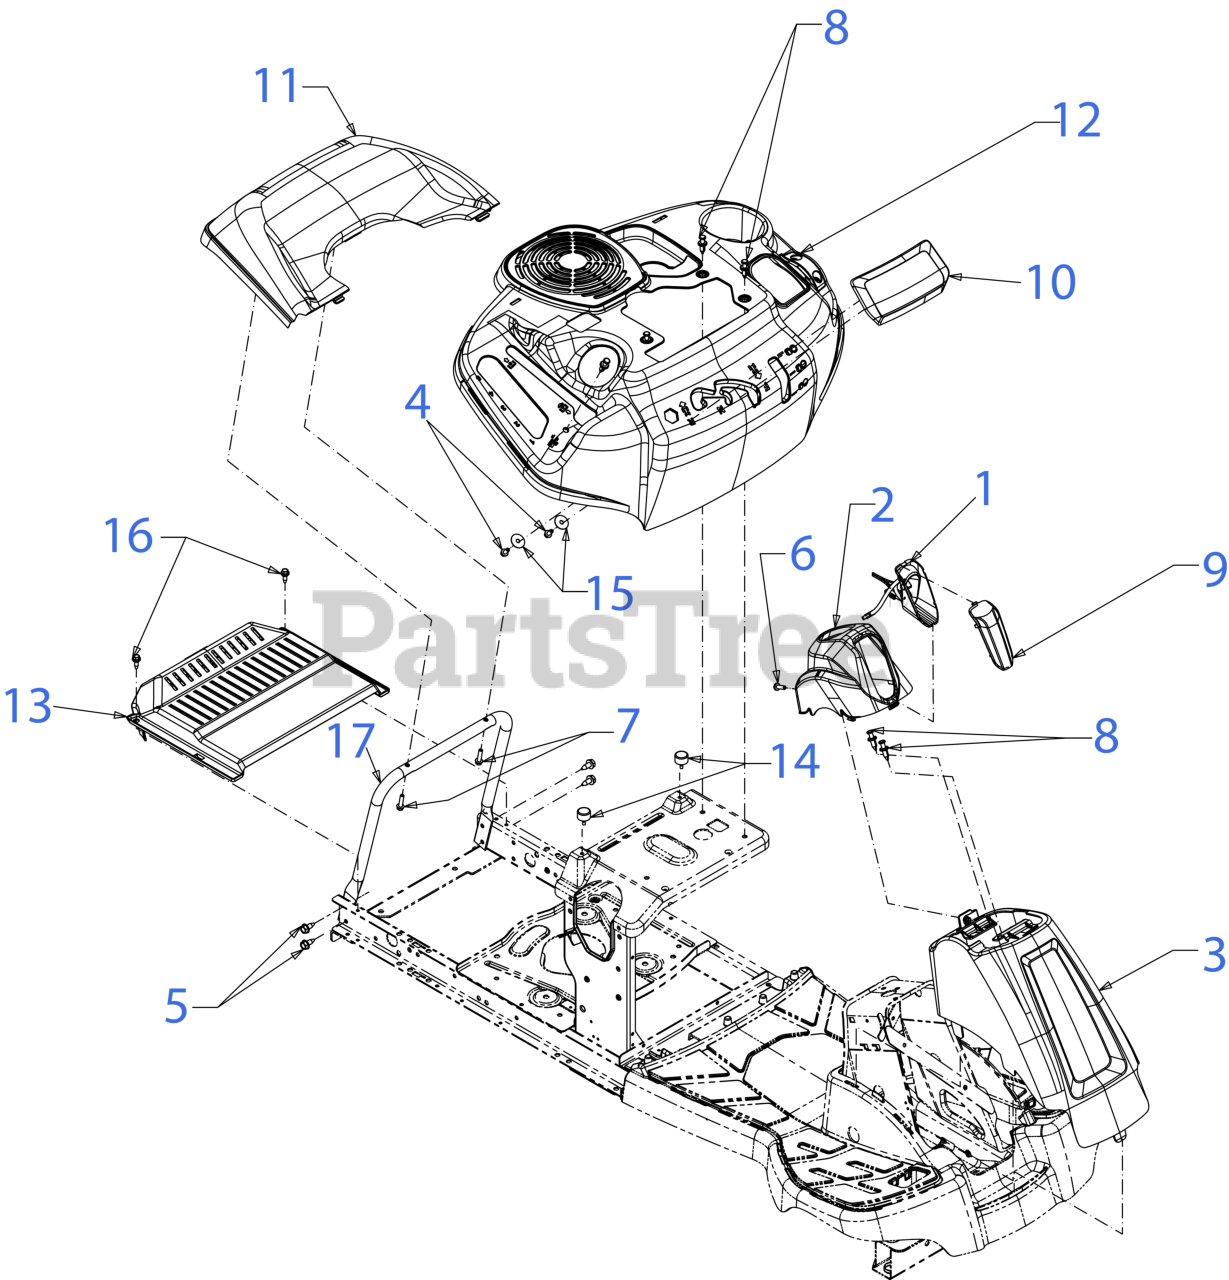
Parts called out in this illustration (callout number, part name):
1	LED HEADLIGHT HARNESS ASSEMBLY
2	COLUMN CAP (LIBERTY RED)
3	COLUMN COVER (LIBERTY RED)
4	HEX SCREW 1/4-15 x .50
5	SCREW 5/16-18 x .750
6	SCREW 1/4-20X.75
7	SCREW 1/4-15 x 1.00
8	PLASTIC RIVET
9	LED HEADLIGHT LENS
10	FENDER COVER
11	REAR COVER (LIBERTY RED)
12	FENDER (B&S W/RMC) (LIBERTY RED)
13	DRIVE COVER
14	BUMPER .62 DIA x .50
15	FLAT WASHER
16	SHOULDER SCREW
